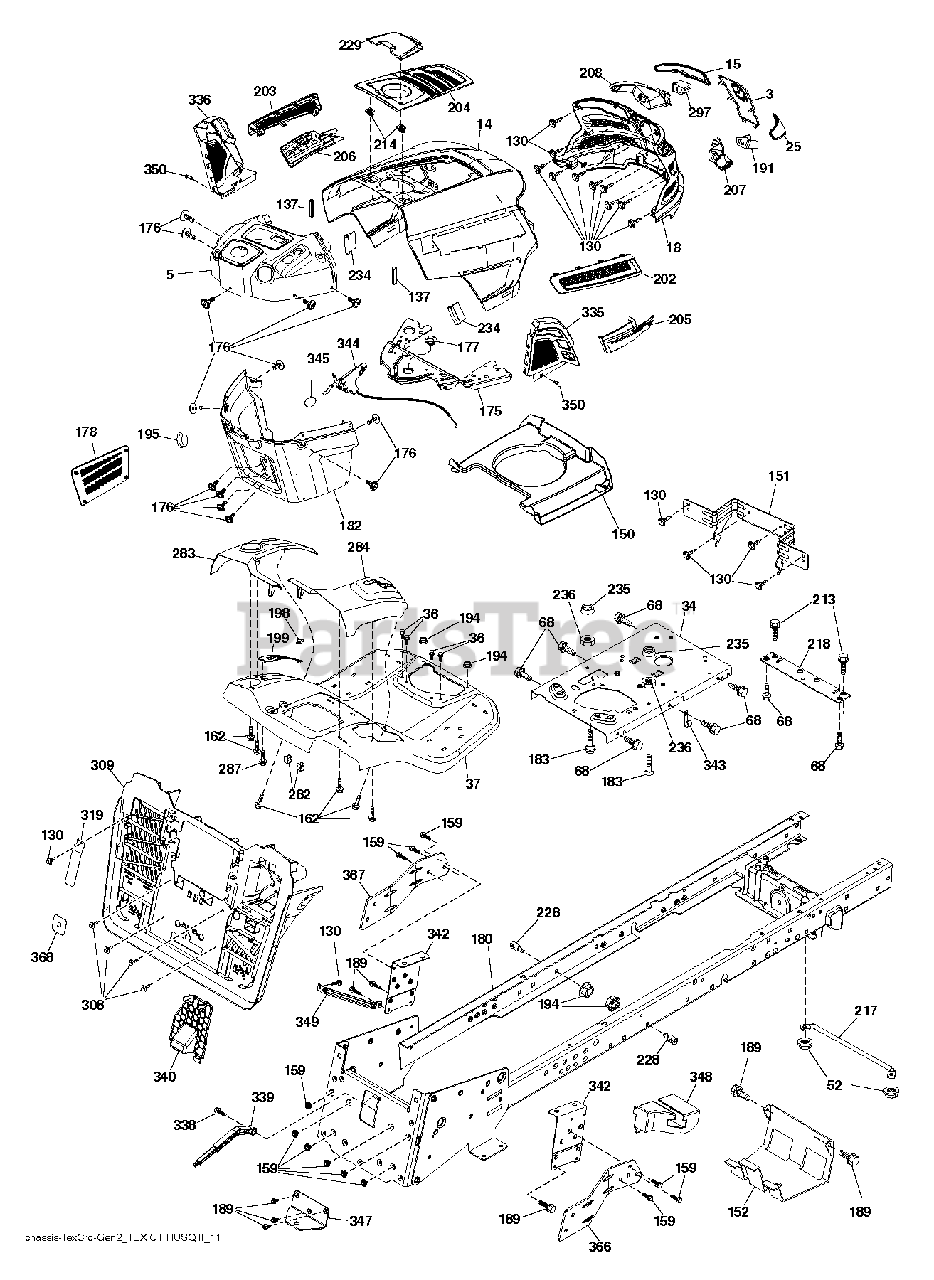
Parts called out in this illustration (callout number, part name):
3	APPLIQUE.SUBASM.GT.HUSQ.II
14	HOOD.ASM.HUSQVARNA.GT.TEX.ORAN
15	LENS.HEADLIGHT.LH.GTII.2011
18	GRILLE.SUBASM.GT.HUSQ.II
25	LENS.HEADLIGHT.RH.GTII.2011
34	PLATE.ENGINE.WELDED.CHASSIS
36	SCREW 5/16"
37	FENDER.TEX.SRD.CRD.FRN.GUARDS
52	LOCKNUT
68	SCREW LT
130	SCREW.#10 X 0.750.BOS
137	BUMPER DASH
150	AIR.DUCT.GTV.BLACK
151	BRACKET.PIVOT.HOOD.GT.HUSQ.II
152	SHIELD.BROWNING.PNT.GT.V2
159	SCREW, 3/8-16X3/4
162	SCREW.HI-LO.CONSOLE
175	PLATE.CROSSMEMBER.HUSQ
176	SCREW.#10-24X5/8.RN.QU
177	BUSHING, STEERING
178	CARGO.ASM.NET.TXGT.W/C
182	DASH DASH LOWER
183	BOLT.5/16-18X1-1/4 FULL THD
189	SCREW
191	INSERT.REFLECTIVE.RH.HUSQ.GTII
194	NUT LOCK HEX FLANGE 5/16-18
195	PLUG.HOLE.DASH.LOWER.12V.BLK
198	INDICATOR.DECK.LIFT.RED
199	PLATE DECK LIFT
202	VENT.SIDE.RH.GT.HUSQ.II.
203	VENT.SIDE.LH.GT.HUSQ.II.498
204	VENT.TOP.EXTERNAL.FILL.GT2.GRE
205	SIDE.TRIM.RH.GT.HUSQ.II
206	SIDE.TRIM.LH.GT.HUSQ.II.GRAY
207	BEZEL LIGHT.RH.GT.II.MYLAR
208	BEZEL LIGHT.LH.GT.II.MYLAR
213	BOLT
214	CLIP.RETAINER.TINNER.
217	ROD.PIVOT.HOOD
218	X-PIECE.HOOD.STOP.NON/
228	STUD.FASTNER.W/ANTI-ROTATE
229	LID.EXT.FILL.GT.HUSQ2.BLACK
234	BUMPER.HOOD.TEX.HUSQVARNA
235	SPACER FENDER
236	NUT.CENTERLOCK.5/16-
282	CLIP.RETAINER.CONSOLE.LT.HUSQ
283	CONSOLE.DECKLIFT.CRDII.498
287	SCREW 1/4X20
297	INSERT.REFLECTIVE.LH.HUSQ.GTII
308	BOLT, 5/16-18 X 1 3/4
309	BACKPLATE.SUBASM.SERV.TEX.CRD.
319	LEVER.BAGGER.TEX.CRD.GEN.BLACK
335	COVER-LH.LOWER.DASH.GT2.BLACK
336	COVER.LOWER.DASH.RH.BLACK
338	BOLT BOLT SHOULDER
339	LEVER LEVER BAGGER
340	BATTERY.DOOR.TEX.CRD.GEN.2,1
342	SUPPORT SUPPORT FENDER
343	CLIP CLIP
344	CONTROL.EZ.MULCH.TEX/CRD
345	RP KNOB.OVAL.TAPERED.3/8-16BLK
347	HITCH HITCH TOW TEX CRD GEN 2
349	BRACKET.SUPPORT.LRVB/CRD
350	CLIP.X-MAS.TREE
366	BRACKET.RH.FRONT.BAGGER.BLACK
367	BRACKET.LH.FRONT.BAGGER.BLACK
368	FULL.LEVER.BAGGER.TEX.CRD
